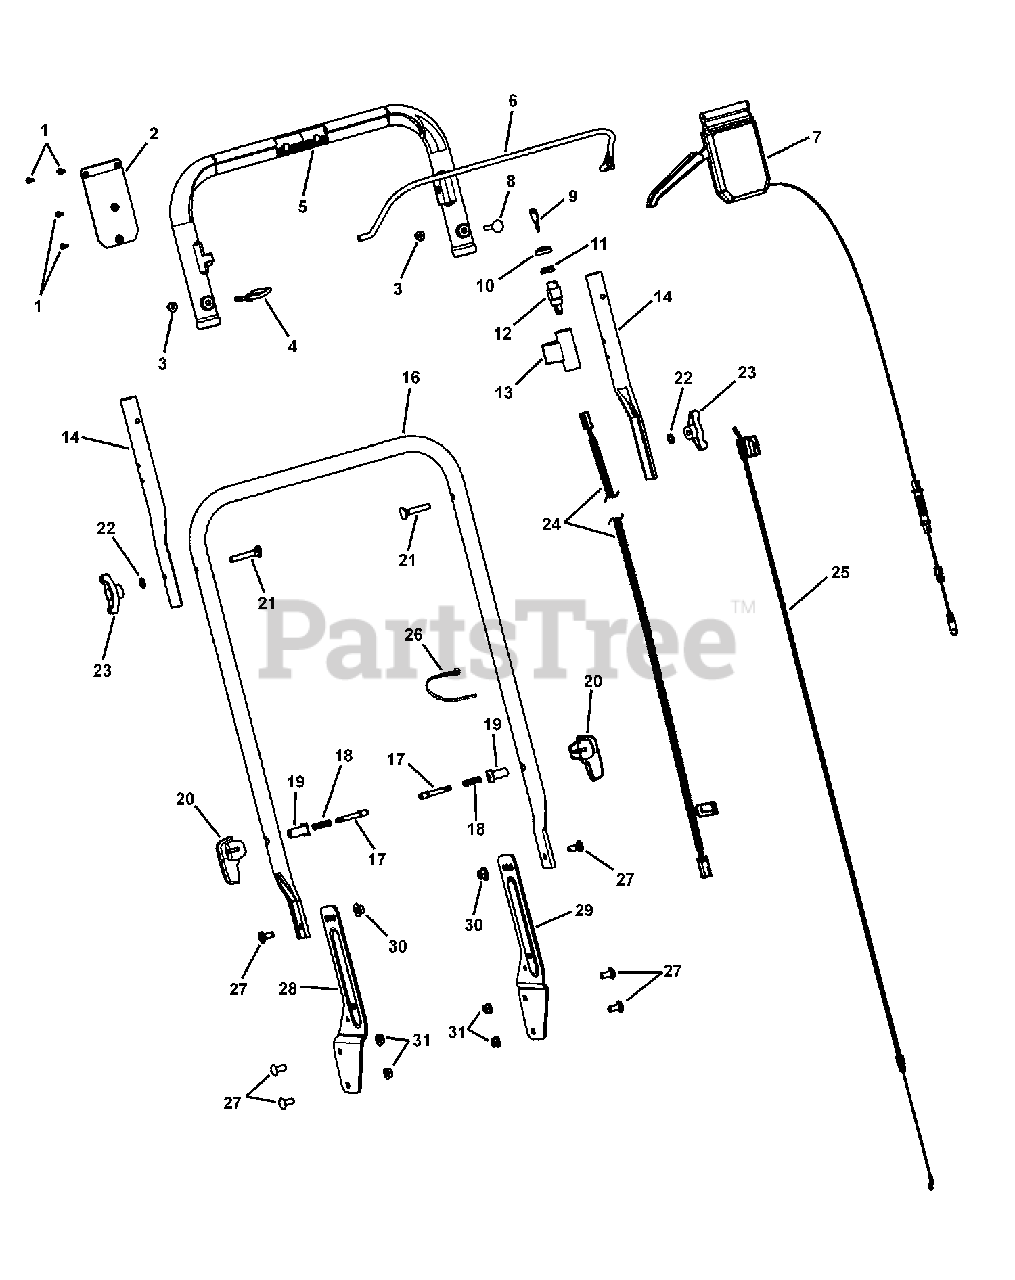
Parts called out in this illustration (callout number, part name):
1	SCREW, #8-16 Torxplus Recessed Pan Head, Twin Helix
2	PLATE, Control Panel- Plastic Handle
3	NUT, 1/4-20, Hex Flange Nyloc
4	ROPE GUIDE (1/4-20 thread)
5	HANDLE, Plastic Upper, WBM
6	BAIL, Plastic Handle, WBM
7	ASSY, Control Head, 21 WBM, RD, Snapper (includes cable & lever)
8	BOLT, 1/4-20 x 1-3/4 Round Head Square Neck, GR 2
9	KEY, Ignition (Pair)
10	CAP, Electric Start
11	NUT, 5/8-32 Electric Start
12	SWITCH, E/S (Start/Run)
13	HOUSING, Snap-On E-Start
14	HANDLE, Connecting 21/22 WBM
16	HANDLE, Lower, 21 WBM, RD
17	PIN, Handle Adjust
18	SPRING, Compression
19	BUSHING, Handle Pin
20	KNOB, Quick Release
21	BOLT, 5/16-18 x 2 Curved Head Square Neck, GR 2
22	WASHER, 5/16 Internal Tooth Lock
23	KNOB, 5/16-18 Wing (Black)
24	WIRE HARNESS, Snapper, RD 21"
25	CABLE, Bail, 21 WBM, RD, Snapper
25	CABLE, Bail, 21 WBM, RD, Snapper, E/S
26	WIRE TIE,11 Inch Standard Black Nylon
27	BOLT, 5/16-18 x 3/4 Round Head Short Square Neck, GR5 YZ
28	BRACKET, Lower Handle, LH 21 WBM
29	BRACKET, Lower Handle RH 21 WBM
30	NUT, 5/16-18 Large Head Center Lock, Black
31	NUT, 5/16-18 Flange Lock, YZ
